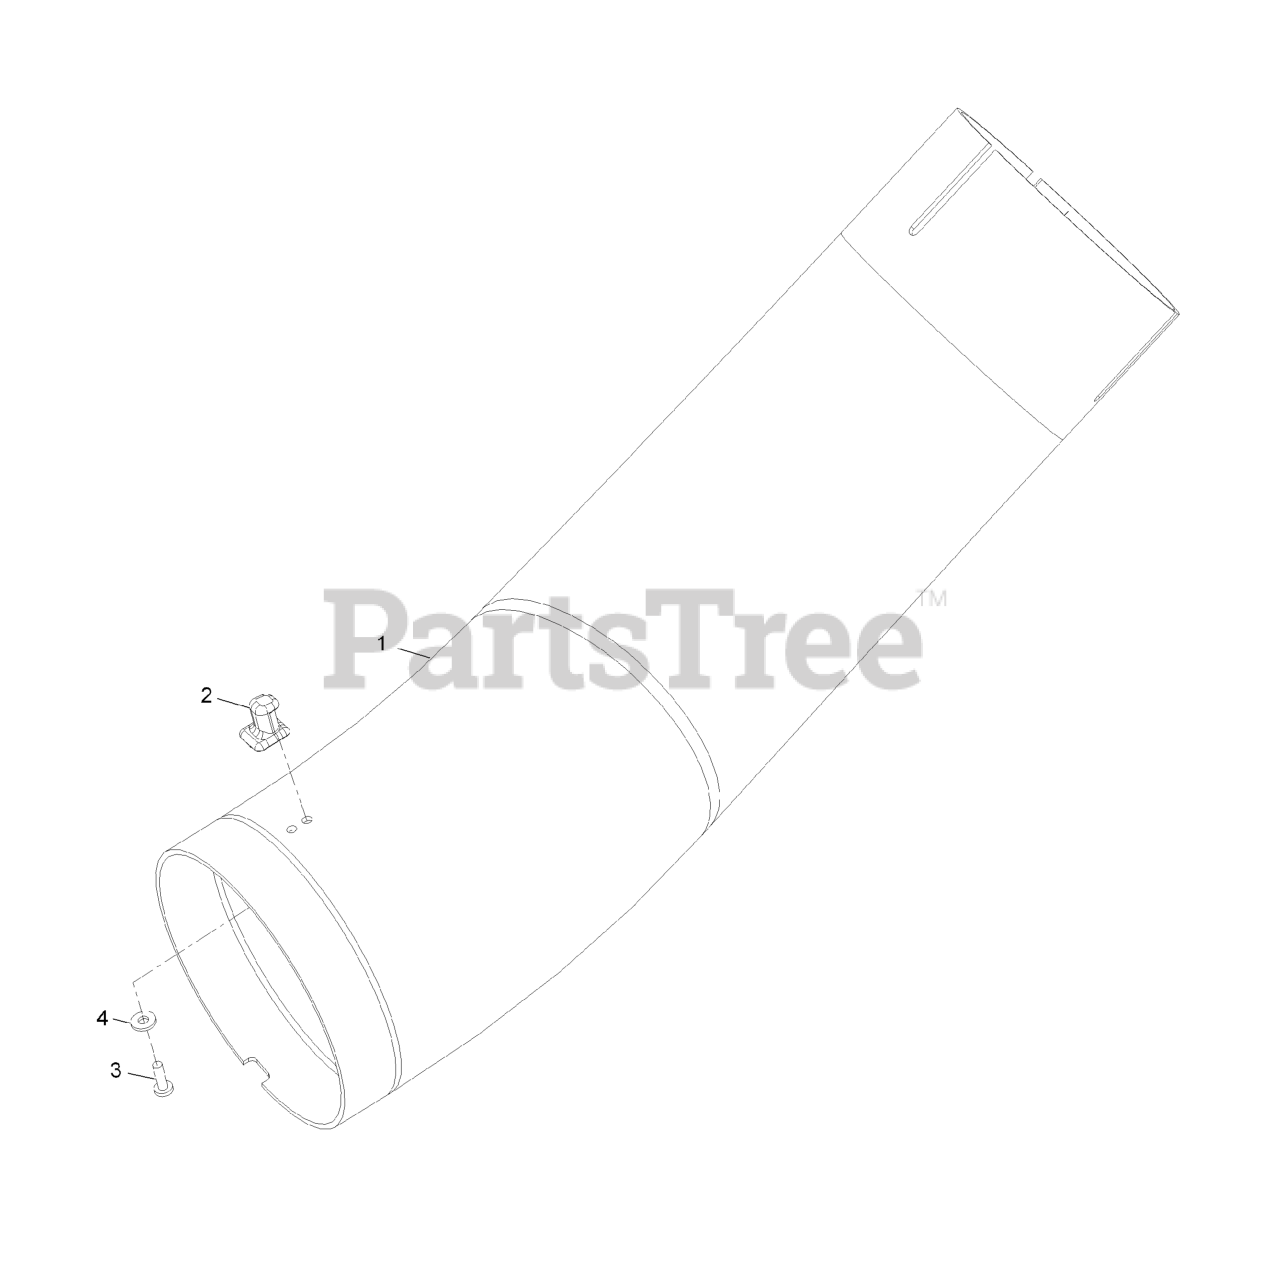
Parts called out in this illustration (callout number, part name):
1	Tube, Lower Short
2	LATCH-KEEPER
3	SCREW-PPH
4	WASHER-FLAT
